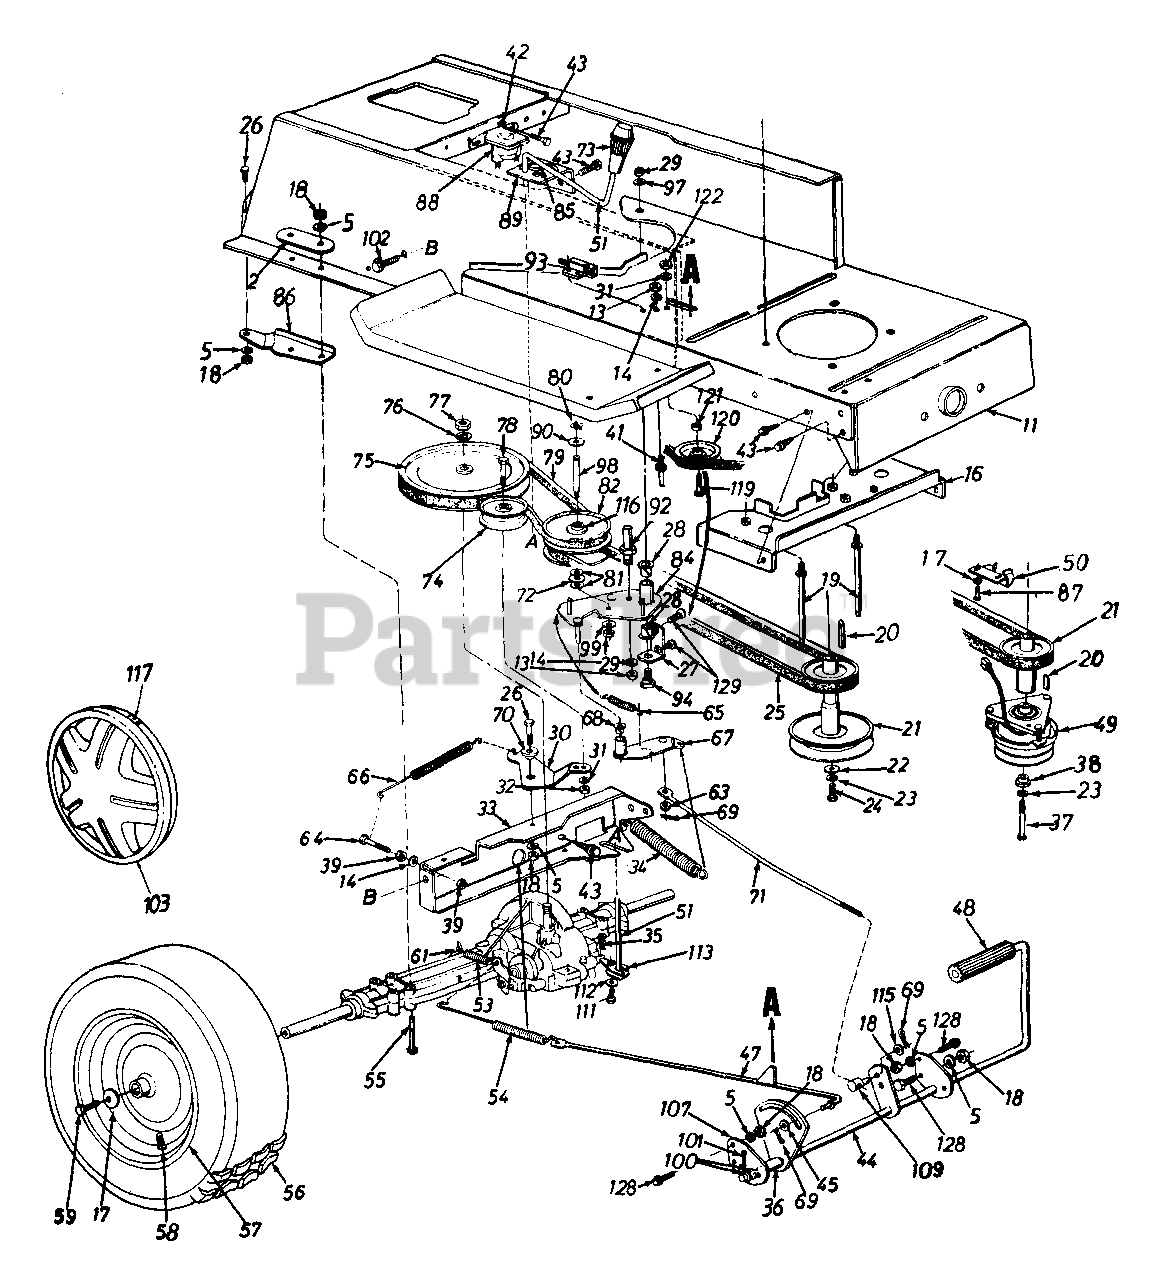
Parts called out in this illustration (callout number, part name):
5	L-Wash. 5/16" I.D.
14	L-Wash. 1/4" I.D.
18	Hex Nut 5/16-18 Thd.
19	Belt Guard Stud 3.6" Lg.
20	Sq. Key 1/4" x 1/4" x 2.00"
21	Engine Pulley
22	Fl-Wash. 7/16" I.D. x 1.25"
23	L-Wash. 7/16" I.D.
24	Hex Bolt 7/16-20 x 1.50" Lg.
25	Variable-Speed Belt
26	Hex Bolt 5/16-18 x .75" Lg.
27	Bearing Shaft Bracket Ass'y.
28	Flanged Nyliner Brg. 5/8" I.D. x .88" Lg.
29	Hex Nut 3/8-24 Thd.
31	L-Wash. 3/8" I.D.
32	Hex Nut 3/8-24 Thd.
35	Inter. Cotter Pin
36	Spacer .63" I.D.
37	Hex Bolt 7/16-20 x 3.25" Lg.
38	Shld. Spacer .445" I.D.
39	Hex Nut 1/4-28 Thd.
41	Belt Guard Pin
42	Ext. L-Wash. 1/4" I.D.
43	Hex Wash. Hd. S-Tap Scr. 1/4-20 x .50" Lg.
47	Brake Rod Ass'y.
48	Foot Pad
49	Electric Clutch
53	Ext. Spring .38" O.D. x 2.5"
54	Ext. Spring .59" O.D. x 7.08" Lg. w/18" Wheels or 46" Deck
55	Hex Bolt 5/16-18 x 3" Lg. Used w/20" Wheels w/o 46" Deck
58	Air Valve
59	Hex Bolt 5/16-24 x .75" Lg.
61	Brake Return Spring Anchor
63	Fl-Wash..34" I.D. x .68" O.D.
64	Hex Bolt 1/4-28 x 1.25" Lg.
65	Ext. Spring
66	Ext. Spring .62" O.D. x 6.12"
68	Flanged Bearing
69	Cotter Pin 3/32" Dia.
70	Shoulder Spacer .27" Lg.
71	Speed Control Link
72	Truss Bearing .56 Dia. x 1.25"
73	Shift Knob
74	Fl-Idler Pulley 3.25" x .75"
76	Bell-Wash..56" I.D. x 1.125"
77	Hex Jam Nut 5/16-18 Thd.
78	Hex Bolt 3/8-24 x 1.75" Lg.
79	Variable Speed Belt
80	Snap Ring .56" Dia.
82	Variable Speed Pulley Ass'y. 5" O.D.
88	Solenoid
90	Teflon Washer.565" I.D.
92	Belt Keeper 3" Lg.
93	Safety Switch (Clutch)
94	Shld. Bolt 3/8-24 x 3.12" Lg.
97	Bell-Wash..38" I.D. x .88"
98	Shaft .56" Dia. x 3.875" Lg.
99	Bell-Wash..39" I.D. x 1.12"
100	Fl-Wash..64" I.D. x .94"
101	Cotter Pin 1/8" Dia. x 1.25"
102	Hex Wash. Hd. Scr. 5/16-18 x .62" Lg.
111	Hex Bolt 1/4-28 x .50" Lg.
112	Bell-Wash..265" I.D. x .75"
113	Shift Lever Link Ass'y.
115	Fl-Wash..385" I.D. x .62"
116	Needle Brgs.
117	Spring Clip
119	Hex Bolt 3/8-16 x 1.25" Lg.
120	Fl-Idler w/Flanges 2.75" O.D.
121	Fl-Wash..39" I.D. x 1.12" O.D.
122	Hex Nut 3/8-16 Thd.
128	Hex Wash. TT-Tap Scr. 5/16-18 x .75" Lg.
129	Hex Wash. AB-Tap Scr. 5/16-18 x .75" Lg.
